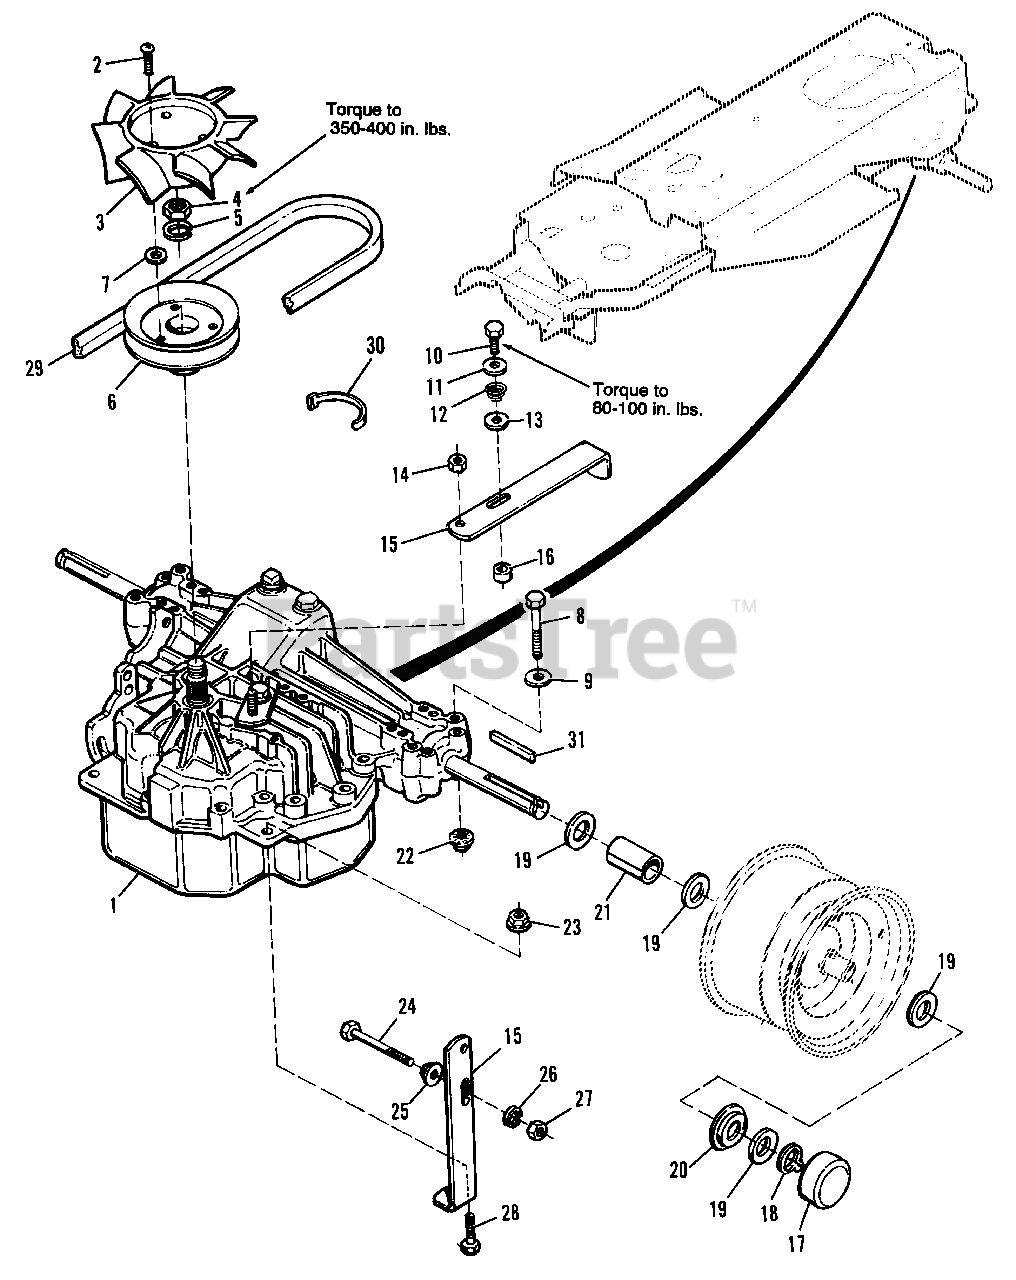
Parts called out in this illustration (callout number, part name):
1	TRANSAXLE, Hydro Gear Model 311-0750
2	SCREW, Taptite, 1/4-20 x 1-1/8
4	JAM NUT, Hex, 1/2-20
5	LOCiCWASHER, 1/2
6	PULLEY ASSY.
7	WASHER, Plain, 1/4
8	CAPSCREW, Hex, 5/16-18 x 2-1/2
9	WASHER, Plain, 5/16
10	SCREW, Taptite, #10-24 x 1-1/4
11	WASHER, 1/4 x 1-1/4 x 1/16
12	SPRING, Conical
13	WASHER, 13/32 x 1-1/4 x 1/16
14	NUT, Hex, Full, Lock, 1/4-20
15	LEVER
18	E-RING, 3/4
19	WASHER, 3/4 x 1-5/8 x 1/8
20	RETAINER, Hub Cap
22	NUT, Hex, Flange Lock, 5/16-18
23	NUT, Hex, Flange Whiz, 5/16-18
24	CAPSCREW, Hex, 5/16-18 x 3-1/4
25	NUT, Hex, Flange Whiz, 5/16-18
26	LOCKWASHER, 5/16
27	NUT, Hex, Full, 5/16-18
28	CAPSCREW, Hex, Whiz, 5/16-18 x 1-1/4
29	BELT, Drive
31	KEY
